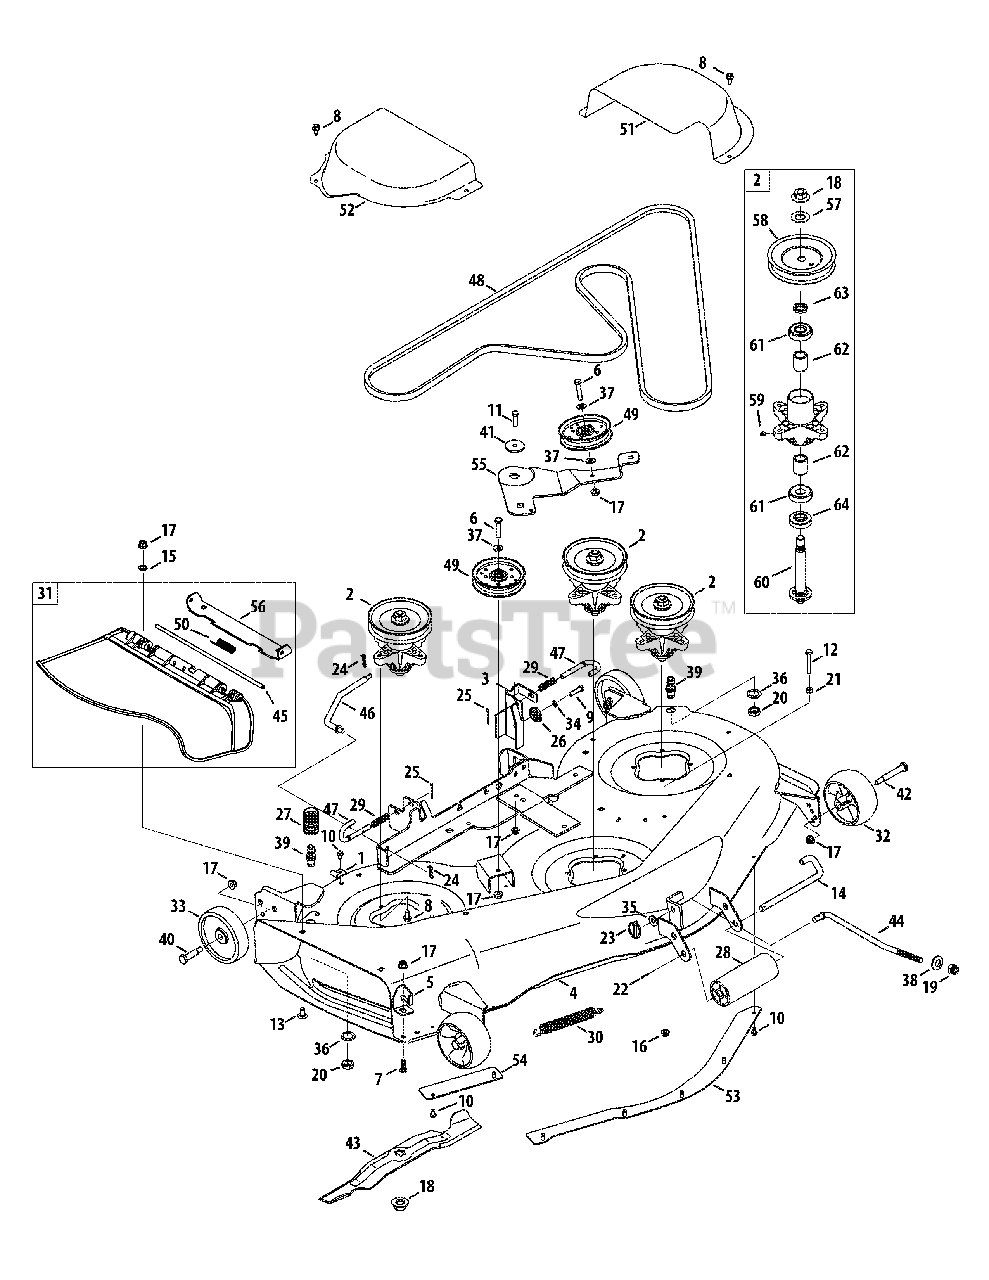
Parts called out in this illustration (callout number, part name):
1	Bracket, Hook, Retainer
2	Spindle Assembly, Pulley, 5.39 Dia.
3	Bracket Assembly, Deck, Hanger LH
4	Deck Assembly, 50"
5	Stop, Chute, Deflector
6	Hex Screw, 3/8-16, 1.75, Gr5
7	Hex Screw, 3/8-16, 1.00, Gr5, Spec
8	Screw, Self-tapping, 5/16-18, .750,
9	Hex Screw, 5/16-18, 1.25, Gr5, Std
10	Screw, Self-tapping, 1/4-20, 0.500
11	Hex Screw, 3/8-16, 1.25
12	Hex Screw, 5/16-18, 2.00, Gr5, Std
13	Bolt, Carriage, 3/8-16, 0.75, Gr1
14	Roller Pin-1/2 Dia. x 7.31
15	Nut, Push, 3/8
16	Nut, Flange Lock, 5/16-18, Nylon
17	Nut, Flange Lock, 3/8-16, Nylon
18	Nut, Flange, 5/8-18
19	Nut, 1/2-13
20	Nut, Hex, M16-1.5
21	Nut, Hex, 5/16-18, Gr5
22	Pin, Cotter, 3/32, 1.0
23	Pin, Lynch, .1875
24	Pin, Cotter, Bow-Tie
25	Pin, Cotter, 1/8 x 1.25
26	Gear, Deck, Adjustment
27	Coupler, Water
28	Roller, Front
29	Spring, Compr’, .53 OD x 1.75
30	Spring, Extension, .94 OD x 6.74
31	Chute Assembly
32	Wheel, Deck, 5.0 Dia. Ball
33	Wheel, Deck 5.0 x 1.38
34	Washer, Lock, 5/16, Regular Duty
35	Washer, Flat, .531 x 1.25 x .100
36	Washer, Lock, 5/8, Int Tooth
37	Washer, Flat, .406 x .875 x .059
38	Washer, Bell, .63 x 1.25 x .18
39	Port, Water
40	Bolt, Shoulder, .496 x 1.525, 3/8-16
41	Spacer, Shoulder, .8840 x .190
42	Bolt, Shoulder, .496 x 2.50, 3/8-16
43	Blade, 17.90 Star 2 In 1
44	Rod, Lift, Deck, Front, 11.7
45	Pin, Hinge, .3175 Dia. x 14.06 ,1
47	Rod, Deck Release
48	Belt, V-Type
49	Pulley, Idler, 4.25"Dia.
50	Spring, Torsion, .44 I.D. x 2.0,
51	Cover, Belt, LH 50"
52	Cover, Belt, RH 50"
53	Skirt, Center, 50"
54	Skirt, RH, 50"
55	Bracket, Idler, 50" w/o Spacer
56	Bracket, Chute 50/54"
57	Washer, Flat, .760 X 1.50 X .120
58	Pulley, Deck, 5.39 Dia.
59	Lube Fitting, 3/16
60	Shaft, Spindle, 5.75 Lg.
61	Bearing, Ball, .787id x 1.85 Od x .551
62	Spacer, .80 x 1.10 x 1.322
63	Spacer, .790 x 1.25 x .175
64	Spacer, .79 x 1.82 x .55lg.
